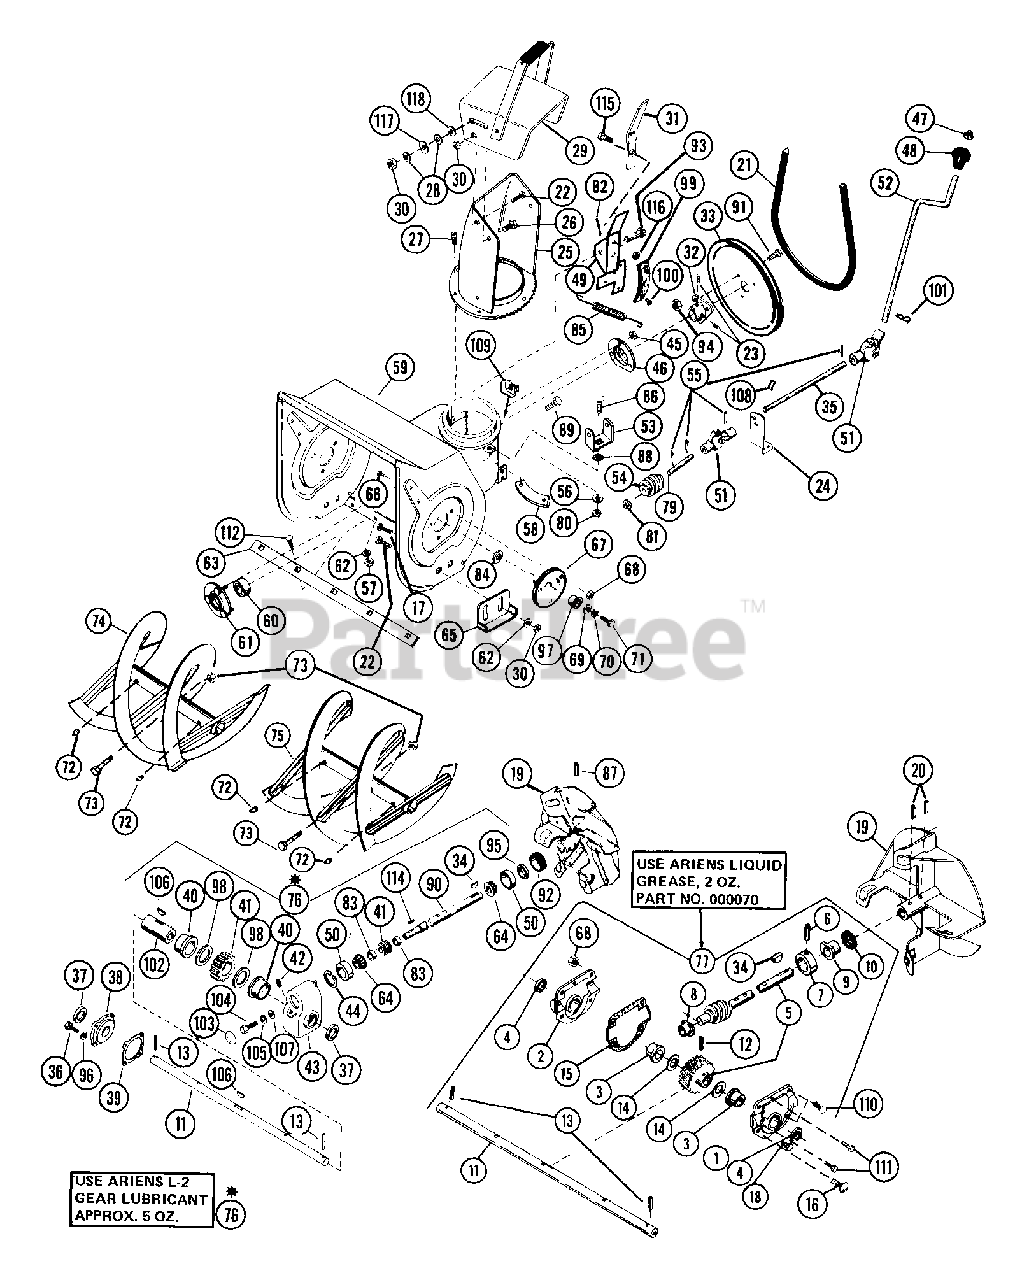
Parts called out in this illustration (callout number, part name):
11	SHAFT, 32" RAKE - 1.00 DIA.
13	PIN-ROLL .188X1.50
17	BLT-RDHDSQSHNK .38-16X1.00 PL
19	FAN - 14"
21	V-BELT, 4L-RAW EDGE
22	BLT-RDHDSQNK .38-16X.75 SHT PL
23	SCR-SET .32-18X.38 SKHCUPNL OH
24	CHUTE CRANK BRACKET
25	DISCHARGE CHUTE
26	BLT-HEX .38-16X.75 PL GR2
27	SCR-TAP 10-24X.375 HWH PL TR
28	WSHR-FL-STL.406X.812X.065PL
29	DEFLECTOR W/ DECAL
30	NUT-LK-CTR .375-16 GR A PL
33	PLY-V 9.0 X 1.25 3BLT
34	KEY-WDRF .188X.875X.375 SAE11
36	BLT-HEX .25-20X.75 PL GR2
37	SEAL 1.625X2.125X.250
38	GEAR CASE COVER
40	BSHG-FLG .683X1.87X1.68X2.250
41	WORM & GEAR SERVICE ASSEMBLY
42	PIPE PLUG
43	GEAR CASE - CAST IRON
44	RG-RTNG-INT 1.781X.062
45	NUT-LK-CTR .250-20 PL
46	BEARING FLANGE
47	CAP, 3/8 ROD YWZC
49	BRAKE ARM ASSEMBLY
50	BRG-CUP 1.781X.475
51	BRAKE ARM ASSEMBLY
52	BRG-CUP 1.781X.475
53	WORM CLEVIS
54	WORM GEAR L. H.
55	PIN-ROLL .125X.75
56	WSHR-LK .313X.062
57	NUT-LK .312-18 GR A PL
58	CHUTE CLAMP
59	BLOWER HOUSING W/DECALS 32
60	BRG-BALL 1.0X2.0X.56
61	BEARING FLANGE
62	WSHR-FL-STL .38X.875X.083 PL
63	SCRAPER BLADE 32"
64	BRG-CONE .750X.61
65	SKID SHOE
66	BLT-SERNK SL .25-20X.50 PL
67	BEARING SUPPORT
68	NUT-LK-FLG .250-20 PL
69	WSHR-FL-STL .511X1.441X.125 PL
70	WSHR-LK .500X.151 HVY PL
71	BLT-HEX .50-13X1.00 PL GR2
72	SPIN DRIVE ZERK FITTING
73	SHEAR BOLT SERVICE ASSEMBLY
74	RAKE, RIGHT-32"(1ID X 15.75OD)
75	RAKE, LEFT-32"(1"ID X 15.75OD)
76	GEAR CASE - CAST IRON
79	WORM SHAFT
80	NUT-HEX .312-18
81	WAVE WASHER .406X.750X.063FH
83	PIN-HAIR INT .06X.18X.77
84	WSHR-FL-STL 1.010X1.505X.062PL
85	SG-TENS .062X.56X8.0 WLD 11
86	BLT-RDHDSQNK .31-18X.75 GR5 PL
87	PIN-ROLL .313X1.75
88	WSHR-LK-EXT .313X.030 PL
89	BLT-SCRHFWH .38-16X.75 PL
90	SHAFT, WORM - 1.00 DIA.
91	BLT-SERRDHD SL .31-18X.87 PL
92	ADJUSTMENT PLUG - 1" SHAFT
93	PIN-CLEV .371X1.16 YWZC
94	NUT-FLG. .312-18 PL
95	SEAL 1.000X1.312X.150
96	WSHR-LK-EXT. 250 ID
97	BSHG-FLG 1.000X1.12X.62X1.50BR
98	WSHR-FL-STL 1.625X2.500X.012
99	BRAKE LINING
100	RVT-TBLR .187X.375 OH ST PL
101	PIN-HAIR INT .08X.38X1.42 YWZC
102	GEAR CASE SHAFT
103	DUST CAP
104	BLT-HEX .31-18X.75 PL GR2
105	WSHR-LK .312X.097 PL HVY
106	KEY-WDRF .25X.875X.375 SAE A
107	WSHR-FL-STL .328X1.0X.094
108	PIN-HAIR INT .08X.38X1.42 YWZC
109	NUT-RETNR .38-16 TINRMAN
110	BLT-RDHDSQNK .25-20X1.25 GR5PL
111	SCR-TAP 10-24X.75 HWH PL TR
112	BLT-RDHDSQNK .312-18X.62 PL
114	KEY-SQ .188X1.0X.188 SAE 8630
117	WAVE WASHER .390X.655X.110
118	WSHR-PLASTIC .390X.875X.062
